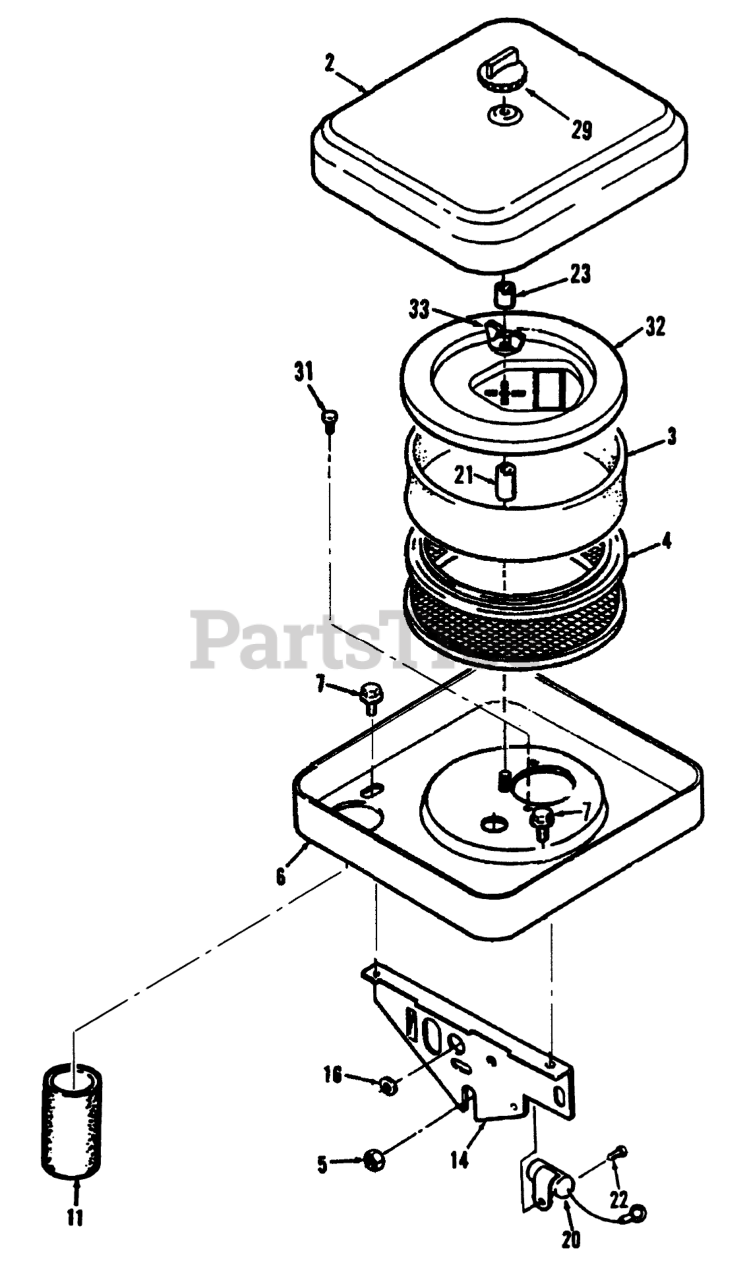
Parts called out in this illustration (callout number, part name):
2	CHROME-AIR CLEANER
3	AIR CLEANER ELEMENT
4	Element-Air Cleaner
5	Washer
6	AIR-CLEANER HOUSING
7	SCREW-TAPPING
11	AIR INTAKE TUBE
14	SUPPORT-AIR CLEANER
16	Grommet
20	Condenser
21	SPACER-1" LG
22	SCREW #10-32 X 5/8
23	SPACER-RUBBER
31	MACHINE SCREW
32	Cover-Element
33	1/4-20 WING NUT
